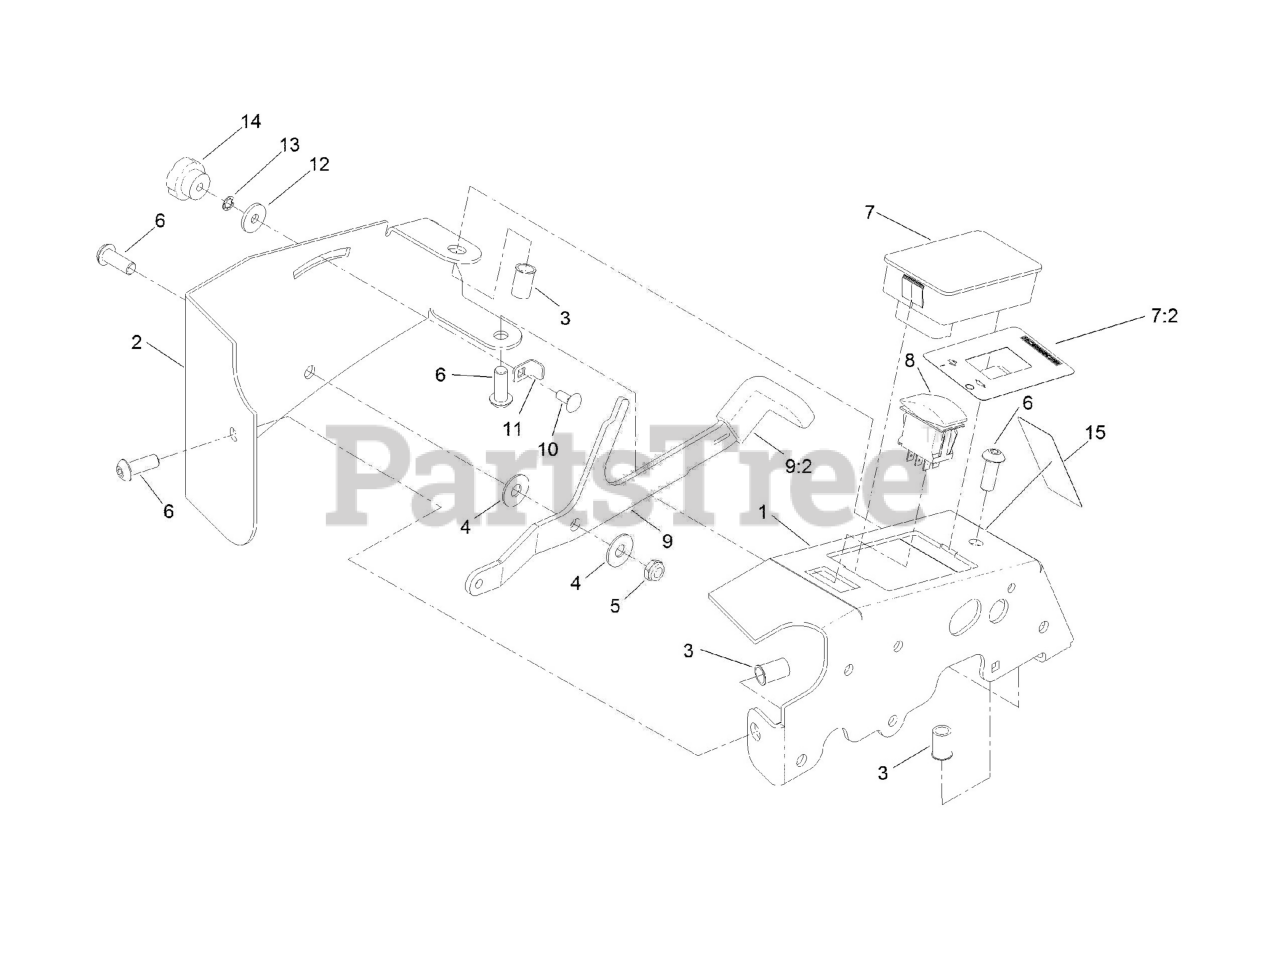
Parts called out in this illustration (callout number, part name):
1	BRACKET-MOUNT
2	COVER-CONTROLLER, SPREADE
3	NUT-CLINCH
6	SCREW-HSBH
7	Spreader Control Module ASM
7:2	DECAL-SPEED, IMPELLER
10	SCREW-CARR
11	BRACKET-GATE, SET
12	WASHER-FRICTION
13	WASHER-LOCK, INT
14	KNOB-CHUTE
15	DECAL-CONTROL, SPREAD
